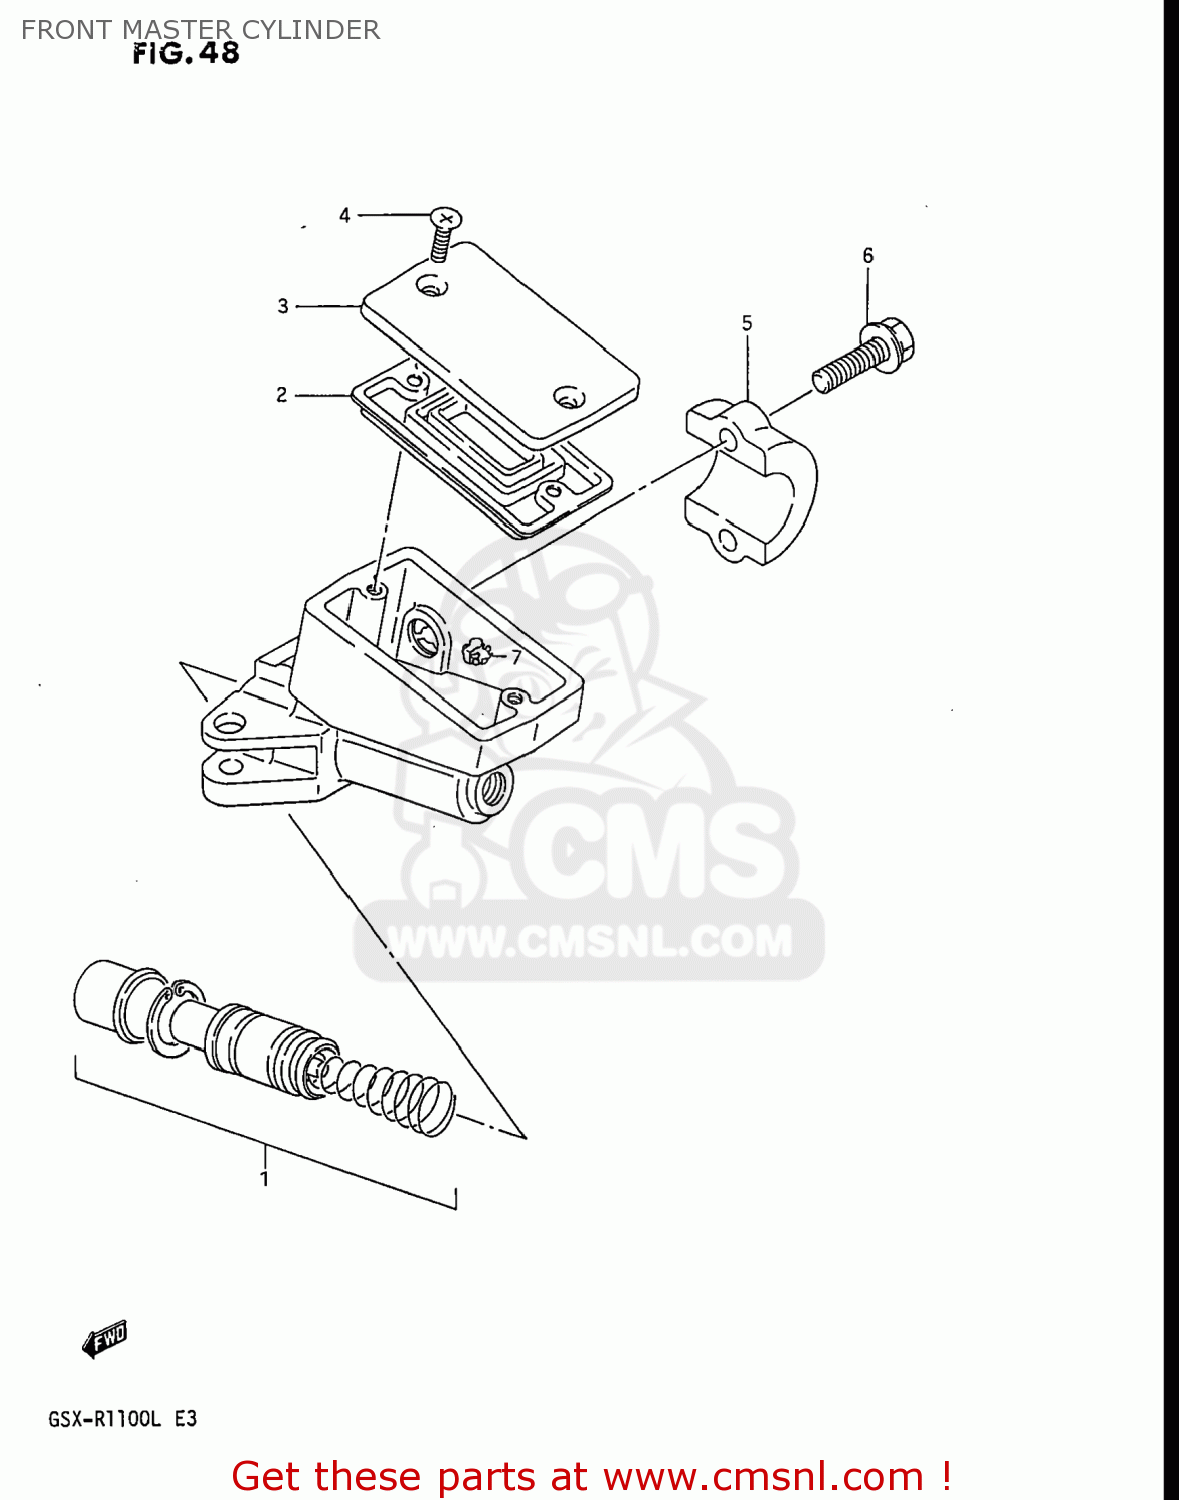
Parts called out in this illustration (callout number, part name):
1	PISTON & CUP SET
2	3-1
3	CAP
4	SCREW
5	HOLDER
6	BOLT
7	PROTECTOR
